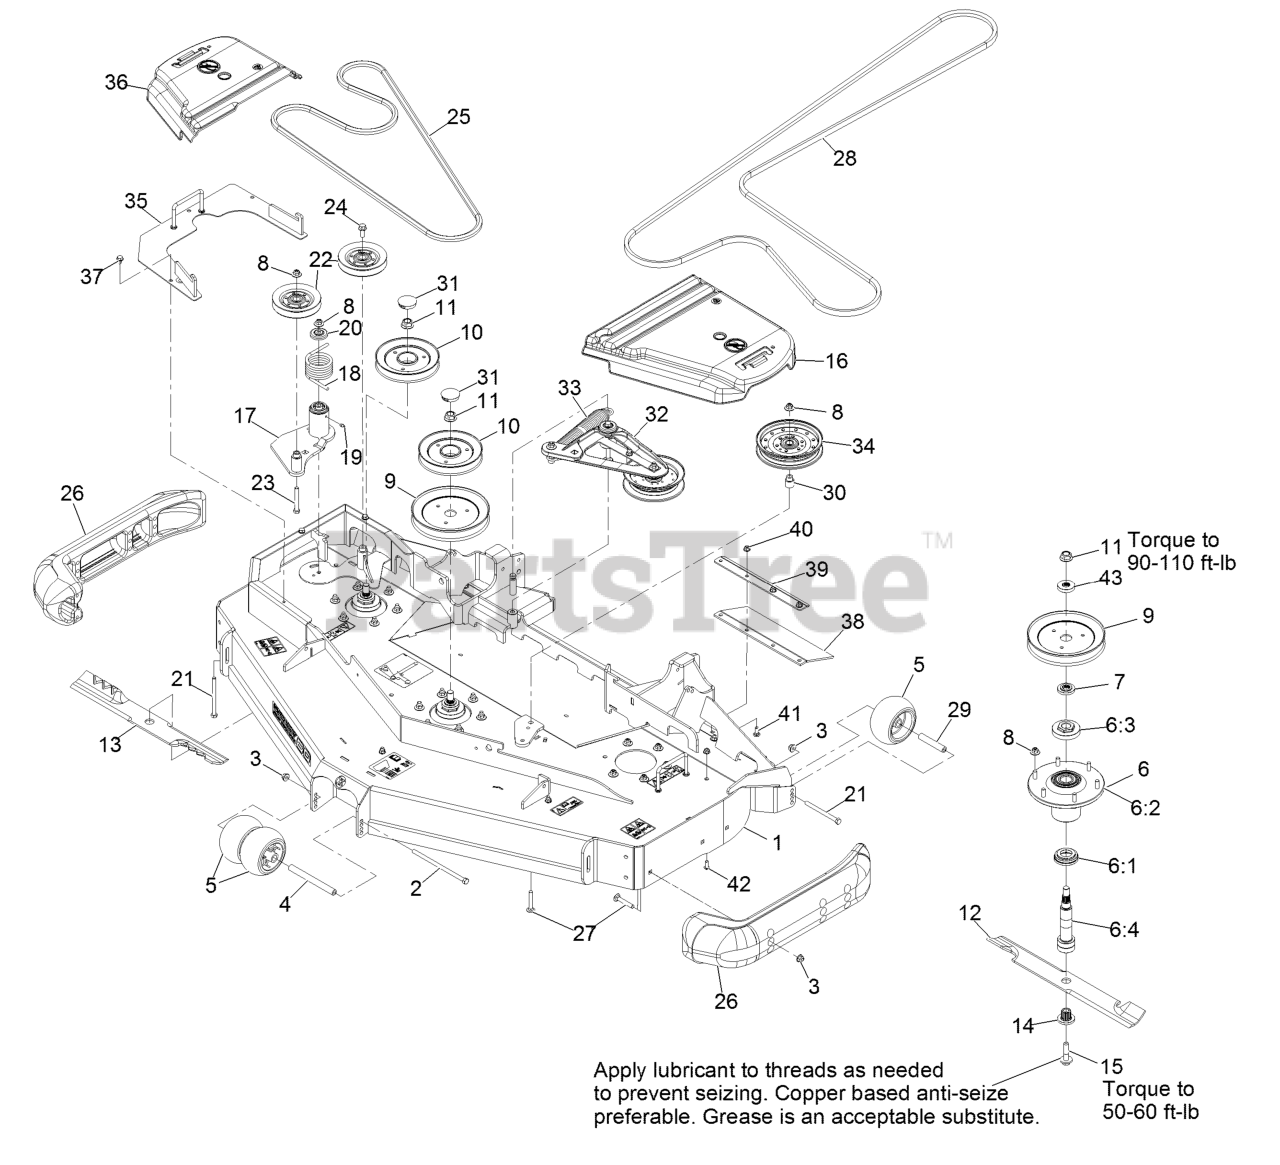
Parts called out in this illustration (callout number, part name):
1	DECK-RD60 NLZ, W/DECALS
2	SCREW-HH
3	NUT-HF, NI
4	SPACER-WHEEL
5	ROLLER-SCALP, ANTI
6	ASM,SPINDLE HOUSING
6:1	GUARD,BOTTOM
6:2	ASM,CUTTER HOUSING
6:3	NUT, SPINDLE 7/8-14
6:4	SPINDLE,DOUBLE SPLINE
7	SPACER,SPLINED STEPPED
8	Nut-Nyloc 3/8-16 Flg
9	SHEAVE,BLADE DRIVE 7.25
10	SHEAVE-RD, REVERSE DRIVE
11	NUT-FLANGE, CENTERLOCK
12	Blade-Extreme 2, 20.50"
13	Blade-Low Lift 20.5, Rd60
13	Blade-Extreme 2-20.50, Rd60
14	BUSHING,SPLINED
15	SCREW,SEMS 1/2-20 X 2.19
16	COVER-BELT, LH
17	IDLER ASM
18	SPRING-TORSION
19	FITTING-GREASE
20	GUARD-TOP
21	SCREW-HH
23	SCREW-HH
24	SCREW-HHF
25	BELT
26	SKID-BUMPER, DECK
27	Bolt-Carriage 3/8-16 X 2 1/4
28	BELT
29	TUBE-SPANNER
30	BUSHING-IDLER
31	PLUG,BLACK NYLON 1.75
32	DECK IDLER ASM
33	SPRING-EXTENSION
35	COVER-DRIVE REVERSE
36	COVER-BELT, RH
38	GUARD-TIRE
39	SUPPORT-OUTER FLAP
40	NUT-HF, NI
41	SCREW-CARR
42	SCREW-HSBH
43	SPACER,SPLINED
